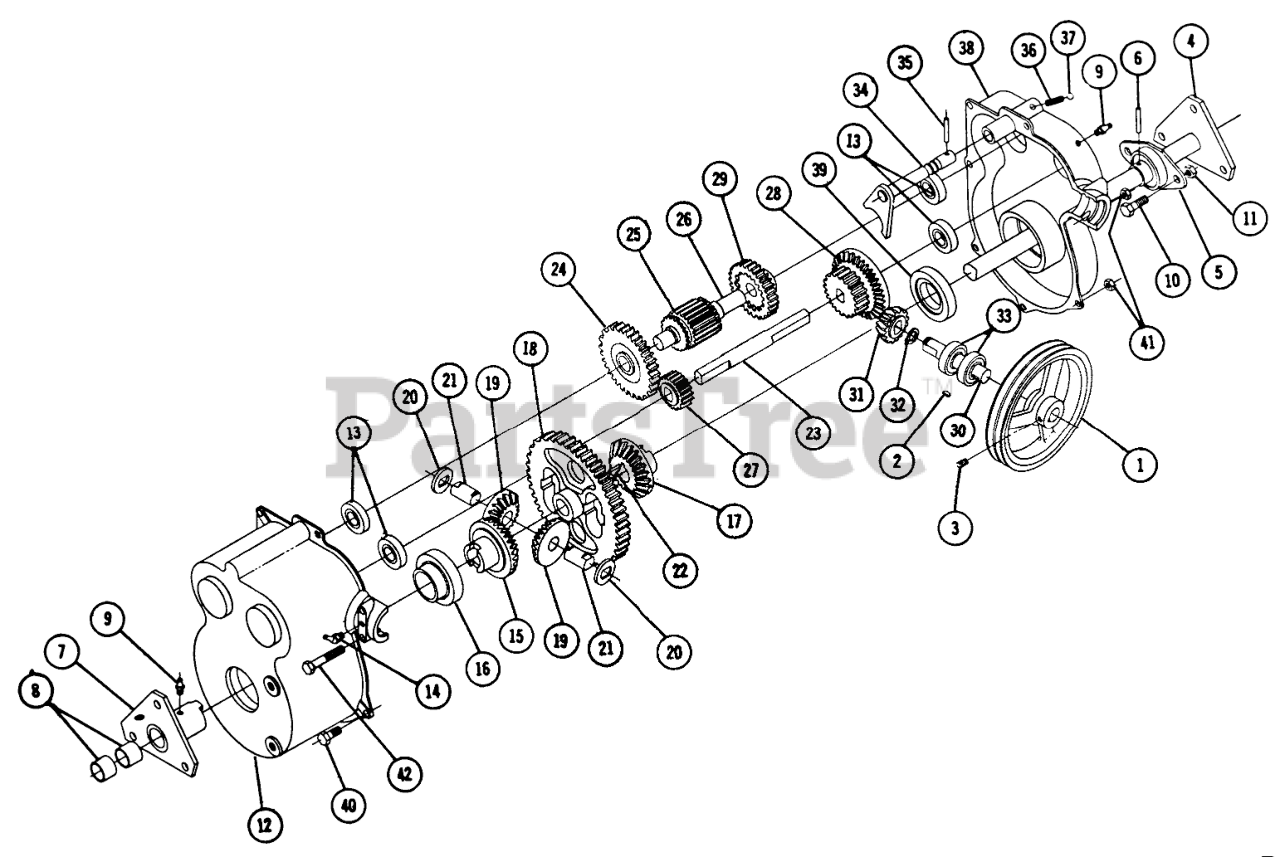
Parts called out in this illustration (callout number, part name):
2	Key
3	Set Screw-Nylok
6	Spirol Pin
8	BUSHING-BRONZE
10	Bolt Hex 3/8-16 x 5/8
14	FITTING-GREASE
22	WOODRUFF KEY
30	Shaft-Input
32	SNAP RING- 5/8 EXT
35	PIN-SPIROL
37	BALL-DETENT
40	Bolt, 5/16-18 X 7/8
41	Nut 5/16-18 Keps
42	Bolt Hex 5/6-18 X 2-1/2
